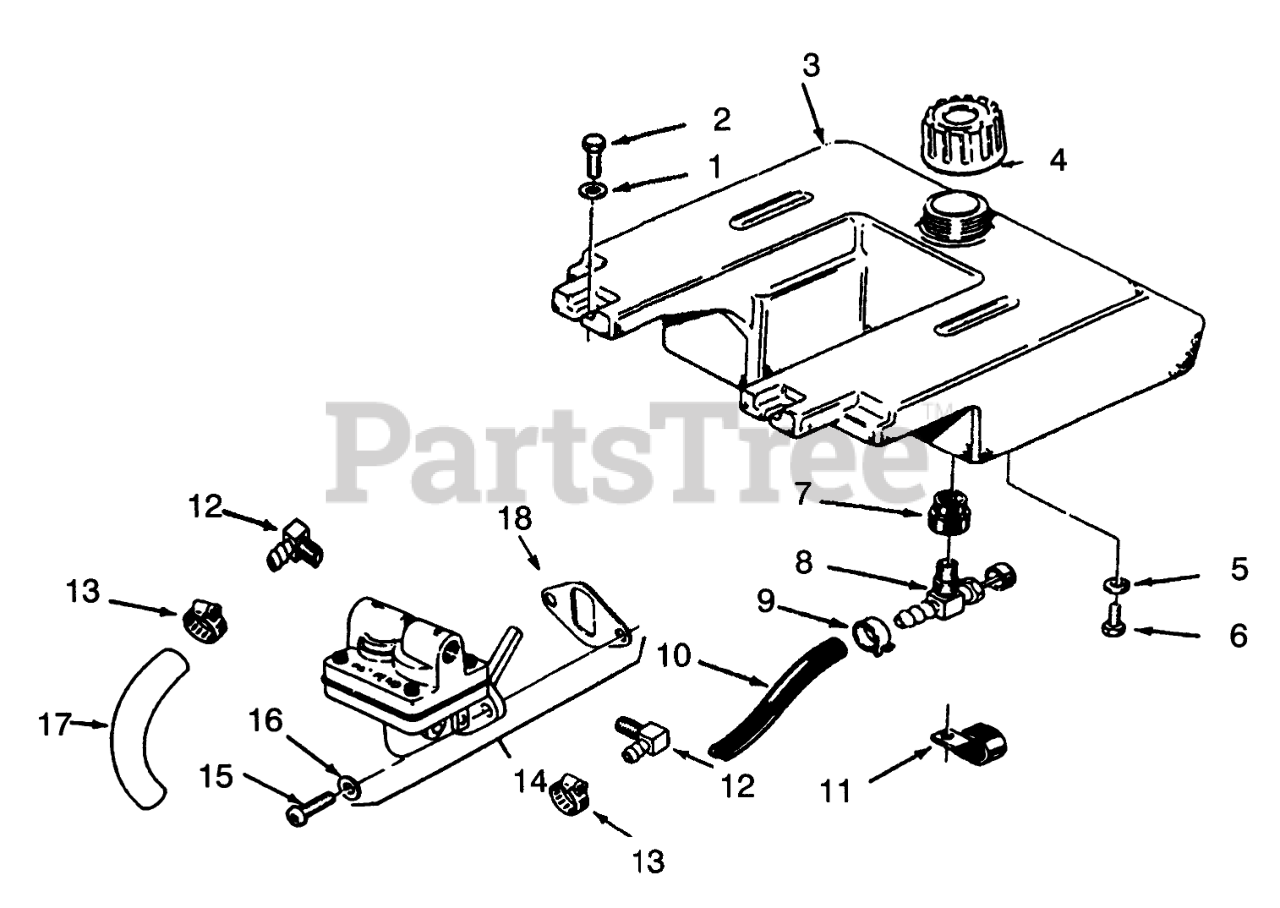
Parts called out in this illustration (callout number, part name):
1	WASHER-FLAT
2	Bolt
3	Tank-Fuel (Incl. Ref. #5 & 7)
4	GAS CAP ASM
5	WASHER-LOCK
6	SCREW-HH
7	BUSHING
8	VALVE-FUEL
9	Clamp
10	Line-Fuel 62"
11	Clamp
12	Connector 90
13	Clamp
14	Pump Assy-Fuel (Incl. Ref. #16 & 19)
15	Screw-Pozidrive
16	Washer
17	Line-Fuel
18	Gasket
